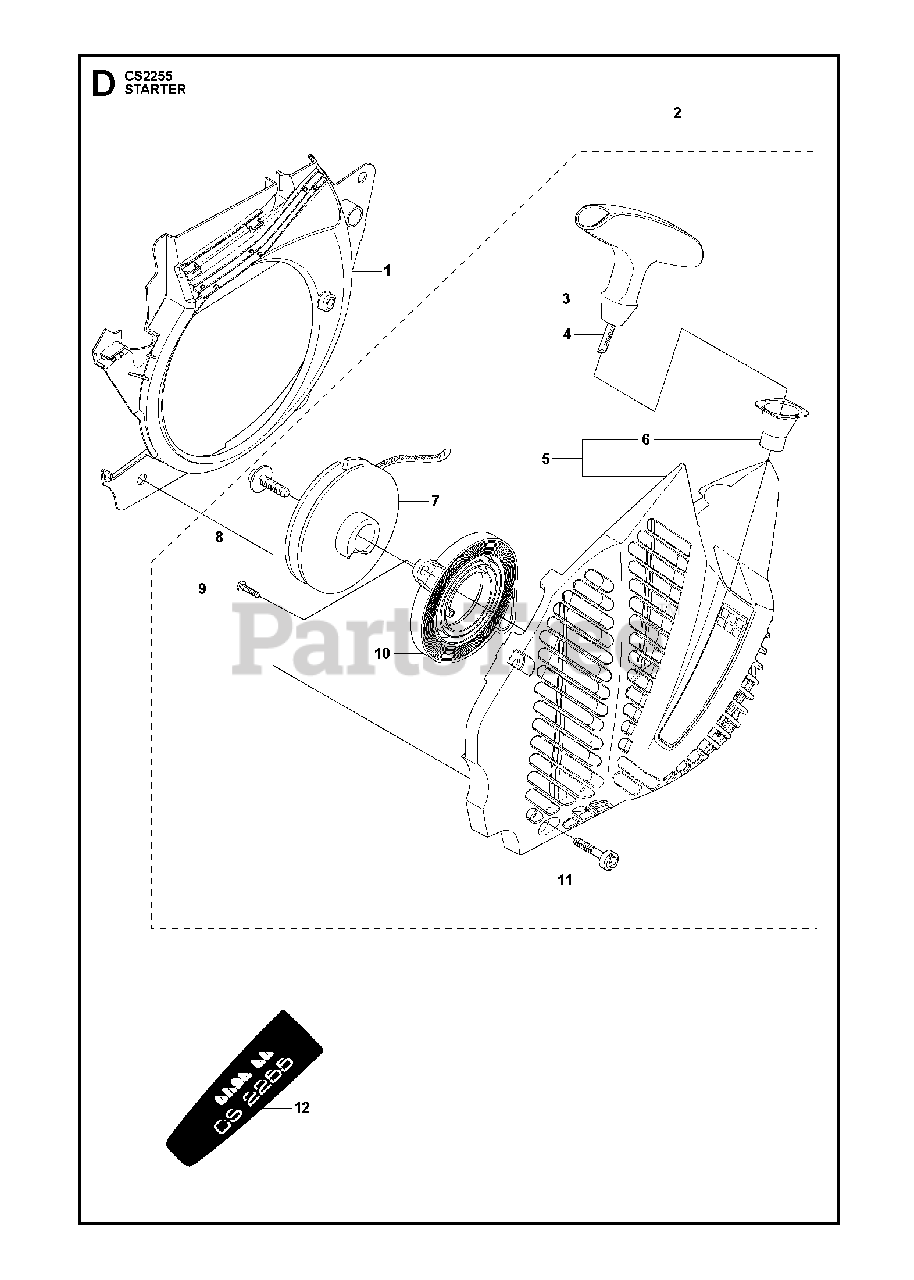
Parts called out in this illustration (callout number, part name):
1	AIR CONDUCTOR
2	STARTER ASSY
3	STARTER HANDLE
4	STARTER ROPE
5	STARTER HOUSING
6	SLEEVE
7	PULLEY
8	SCREW
9	SCREW
10	RETURN SPRING
11	SCREW
12	DECAL
